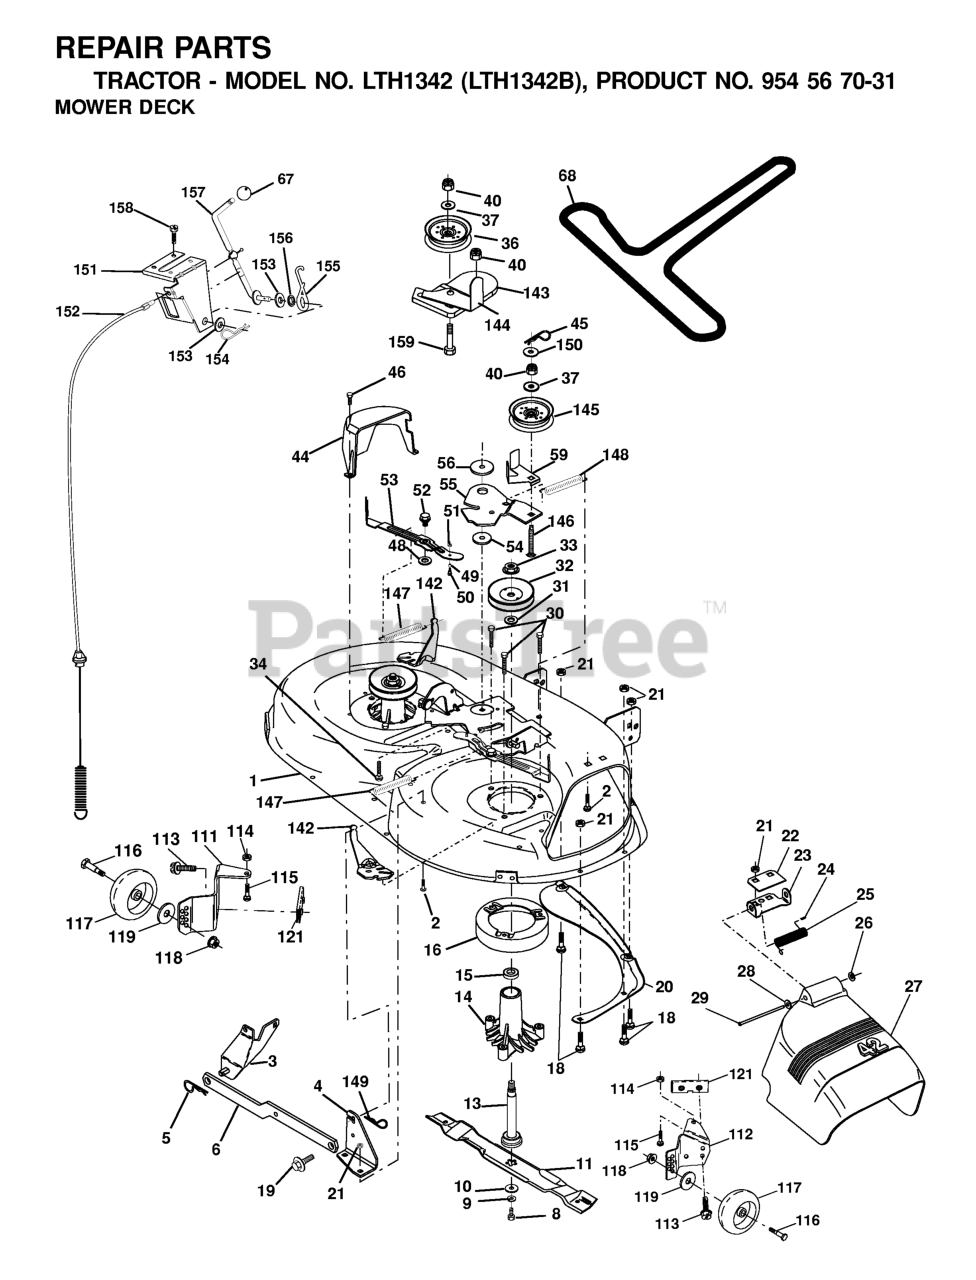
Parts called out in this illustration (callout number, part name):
1	DECK SVC 42"
2	RP BOLT 5/16-18 X3/4 ZN/YEL GR
3	BRKT ASM SWAY BAR
4	BRACKET ASM DECK 42"
5	RETAINER-SPRNG RB
6	REAR SUSP ARM
8	BLADE BOLT
9	LOCKWASHER
10	WASHER.BLADE
11	Blade Mower 42" High Perf.
13	SHAFT ASM VENT
14	HOUSING.MANDREL.VENTED (MACHD)
16	STRIPPER.MANDREL.ROUND.BLACK
18	BOLT
19	BOLT SHD 5/16-18
20	BAFFLE.VORTEX
21	LOCKNUT
24	CAP-SLEEVE LT
25	SPRING TORSION
26	NUT PUSH M
28	Washer 11/32 x 5/8 x 16 Ga SD
29	ROD.HINGE
30	SCREW THDROL ROLLING WASHER HD
31	WASHER
32	PULLEY MANDREL
33	NUT
36	PULLEY.IDLER.FLAT
37	WASHER
44	GUARD MANDREL LH BLACK
45	RETAINER M
46	SCREW.1/4-20X5/8
49	ROLLER ASM CAM FOLLOWER
52	BOLT.SHOULDER.5/16-18
53	ARM
54	HARDENED WASHER
55	ARM IDLER 42"
56	SPACER RETAINER
59	GUARD TUV IDLER
67	KNOB T (3/8 HOLE)
68	BELT V SECONDARY
113	Screw Tapping 5/16-18 Unc
114	NUT
115	BOLT.CARR.5/16-18X1/2
116	BOLT M
117	WHEEL.GAUGE.STANDARD
118	LOCKNUT
119	WASHER.5/16.FLAT.STE.STD.
143	BRKT ARM IDLER 42"
144	KEEPER BELT 42" CLUTCH
145	PULLEY.IDLER.FLAT.PLATED
146	BOLT CARRIAGE IDLER
147	SPRING EXTENSION
148	IDLER RETURN SPRING
149	SPRING.RETAINER.YELLOW.ZINC
151	BRACKET.CLUTCH.CABLE
152	CLUTCH CABLE 42"
153	WASHER FLAT 3/8"
154	SPRING RETAINER
155	SPRING RETENTION LEVER
156	SPACER.CLUTCH.CABLE
157	ROD CLUTCH CABLE 3/8"
158	SCREW LT
